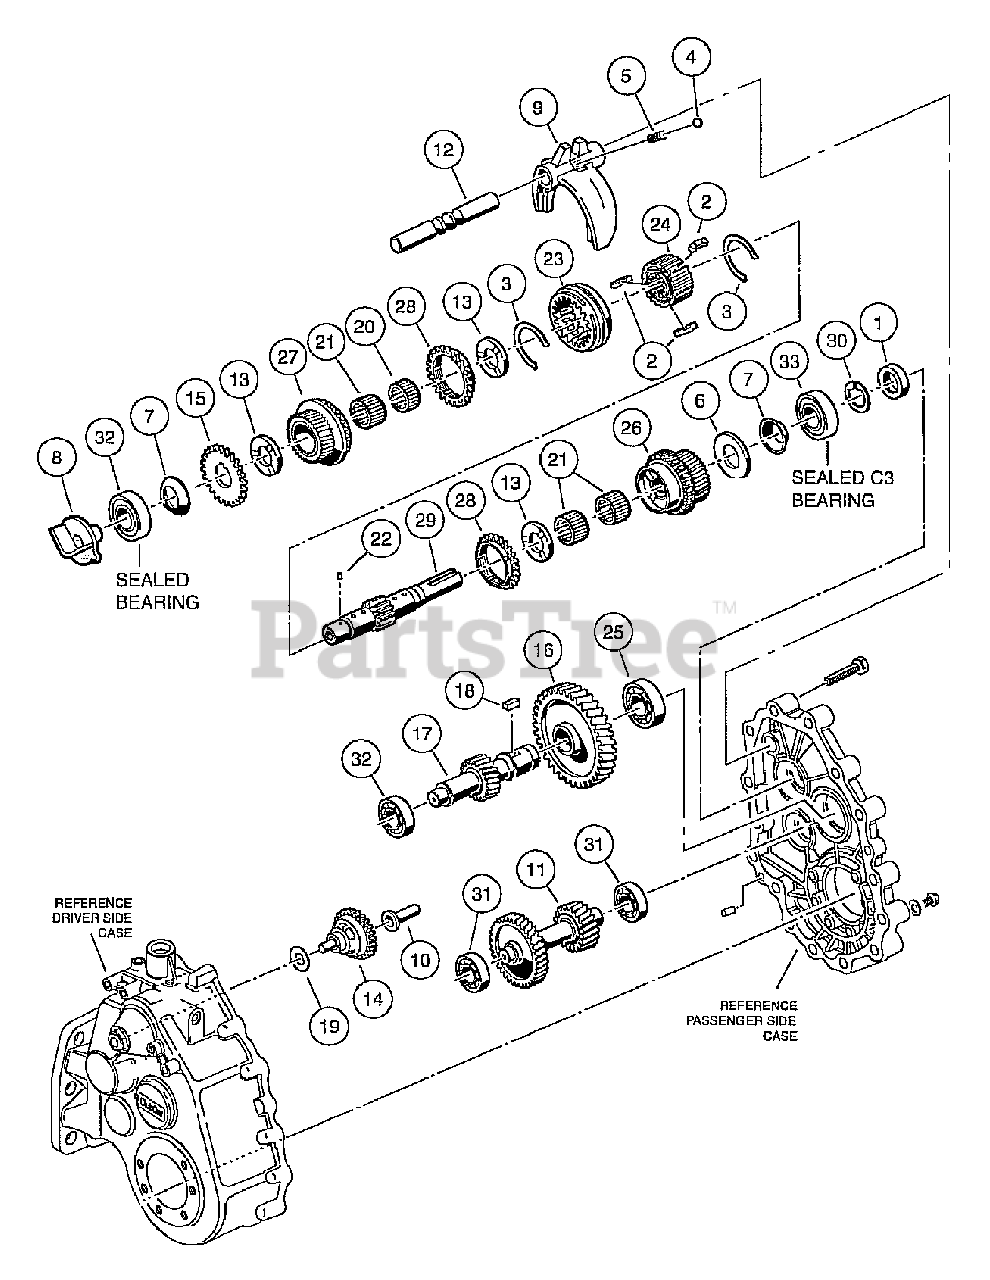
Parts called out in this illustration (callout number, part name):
2	Synchro Insert
3	Synchro Spring
4	Shifter Ball
5	Shifter Spring
6	Washer, Thrust
7	Washer. Spring
9	Fork - Shift
10	Sleeve, Governor
11	Gear, Cluster
12	Rod, Shift
13	Plate, thrust
14	Governor Assembly
15	Gear, Spur
16	Gear, Helical
17	Gear, Helical
20	Bearing, Needle
21	Needle Bearing
22	Pin, .116" Dia X 0.264 Dowel
23	Sleeve, Synchro
24	Hub, Synchro Clutch
25	Bearing, Ball
26	Gear Assembly, 16-Degree Synchro
27	Gear Assembly, 16-Degree Rear Synchro
28	Ring, 16-Degree Synchronizer
29	Shaft, Trans, with Circlip
32	Bearing, Ball, Sealed
33	Bearing, Ball, Sealed
